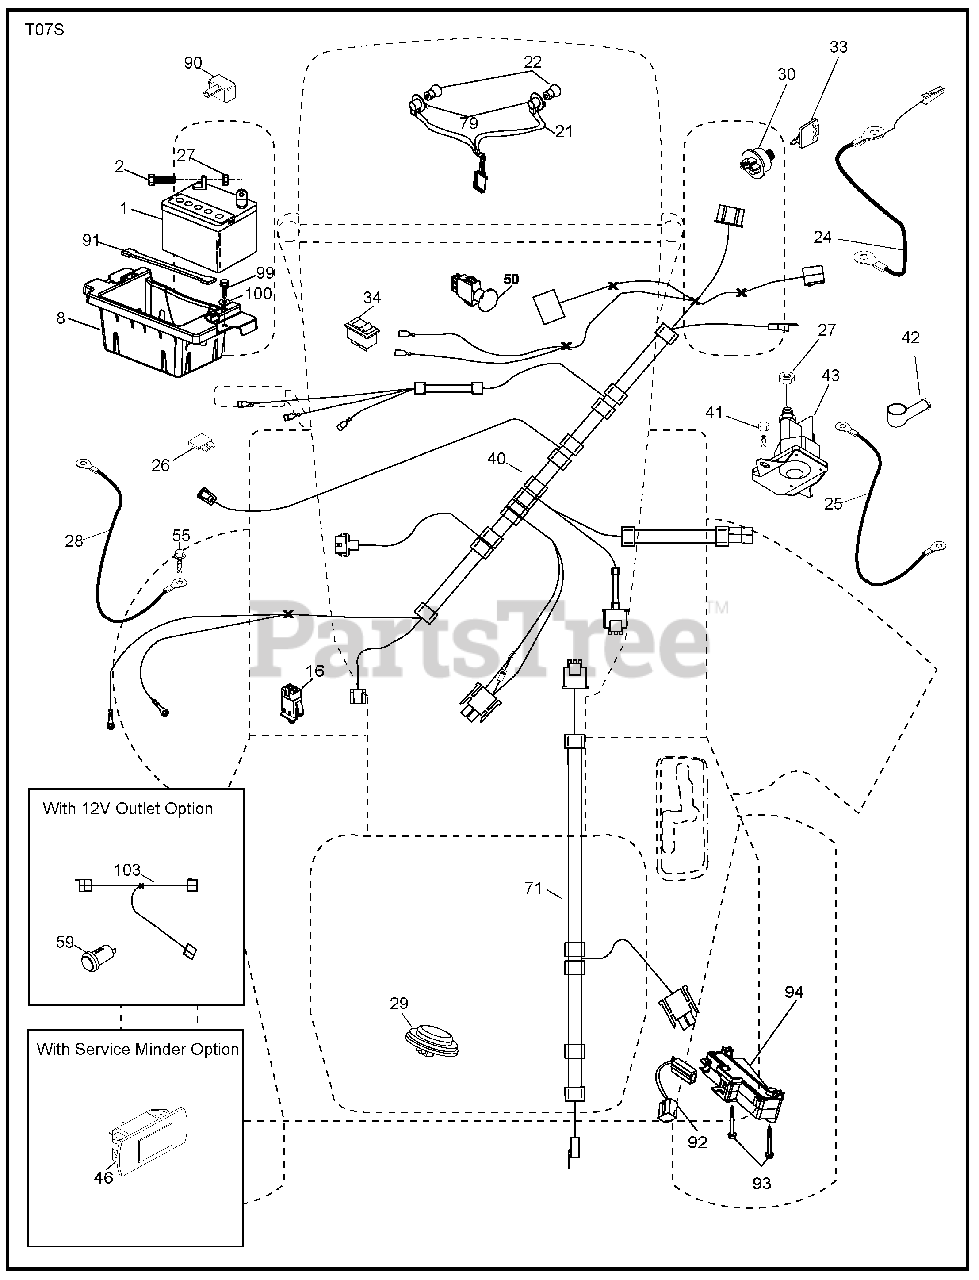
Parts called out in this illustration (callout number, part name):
1	Battery
2	Bolt Hex Head 1/4-20 x 3/4
8	Box Battery
16	Switch Interlock Push-In
21	Harness Socket Light W/4152J
22	Bulb Light
24	Cable Battery
25	Cable Start Red 17.5"
26	Fuse
27	Nut Keps Hex 1/4-20 unc
28	Cable, Ground
29	Switch, Seat
30	Switch, Ignition
33	Key/Chain
34	Switch Light / Reset
40	Harness Ign. Dash
41	Screw Thd Cut 1/4-20 x 1/2
42	Cover, Terminal
43	Solenoid
46	Gauge Hourmeter
50	Switch, PTO
55	Screw Thdrol 5/16-18 x 3/4 TYTT
71	Harness Ignition, Chassis
79	Bulbholder Asm. Incan Descent
90	Cover Terminal Battery
91	Strap Battery Mount Front
92	Harness Pigtail Consle ROS
93	Screw Plastite 10-14 x 2.0
94	Module Reverse ROS
99	Screw Hexwsh Thdrol 1/4-20 x 3/4
100	Washer 9/32 x 7/8 x 16 Ga.
